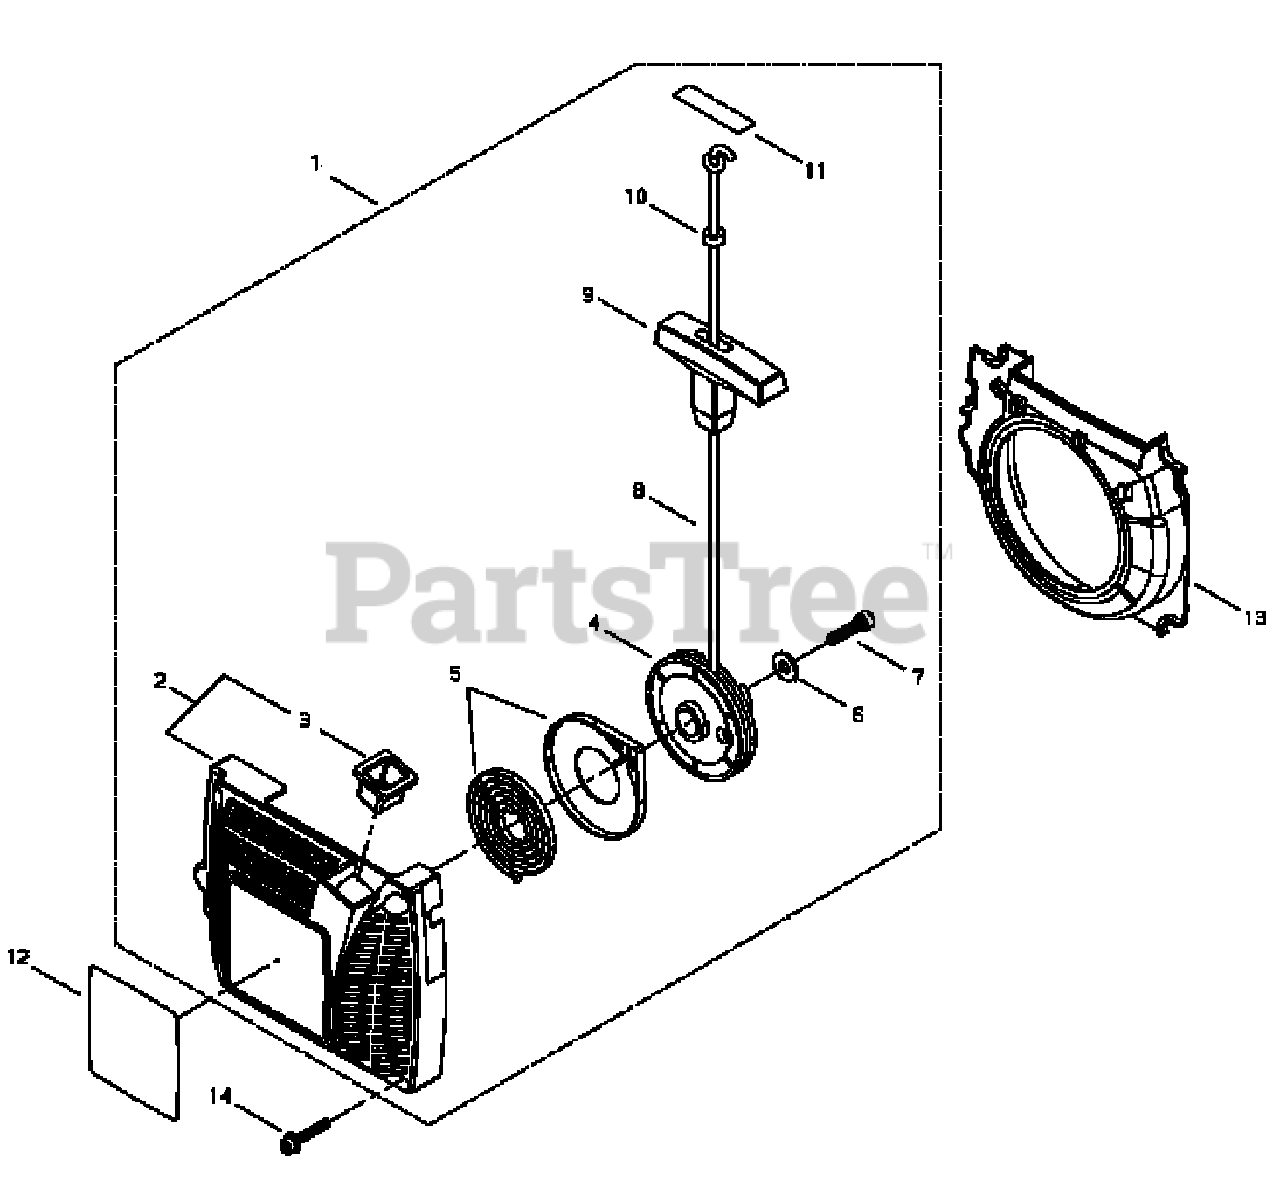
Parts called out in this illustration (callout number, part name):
1	STARTER ASSY
2	CASE, STARTER
3	GUIDE, ROPE
4	REEL
5	SPRING, RECOIL
6	WASHER
7	BOLT 5×12
8	ROPE
9	RECOIL, KNOB
10	KNOB, STOPPER
11	TAPE
12	LABEL, TRADE
13	PLATE, AIR
14	BOLT M4×16
